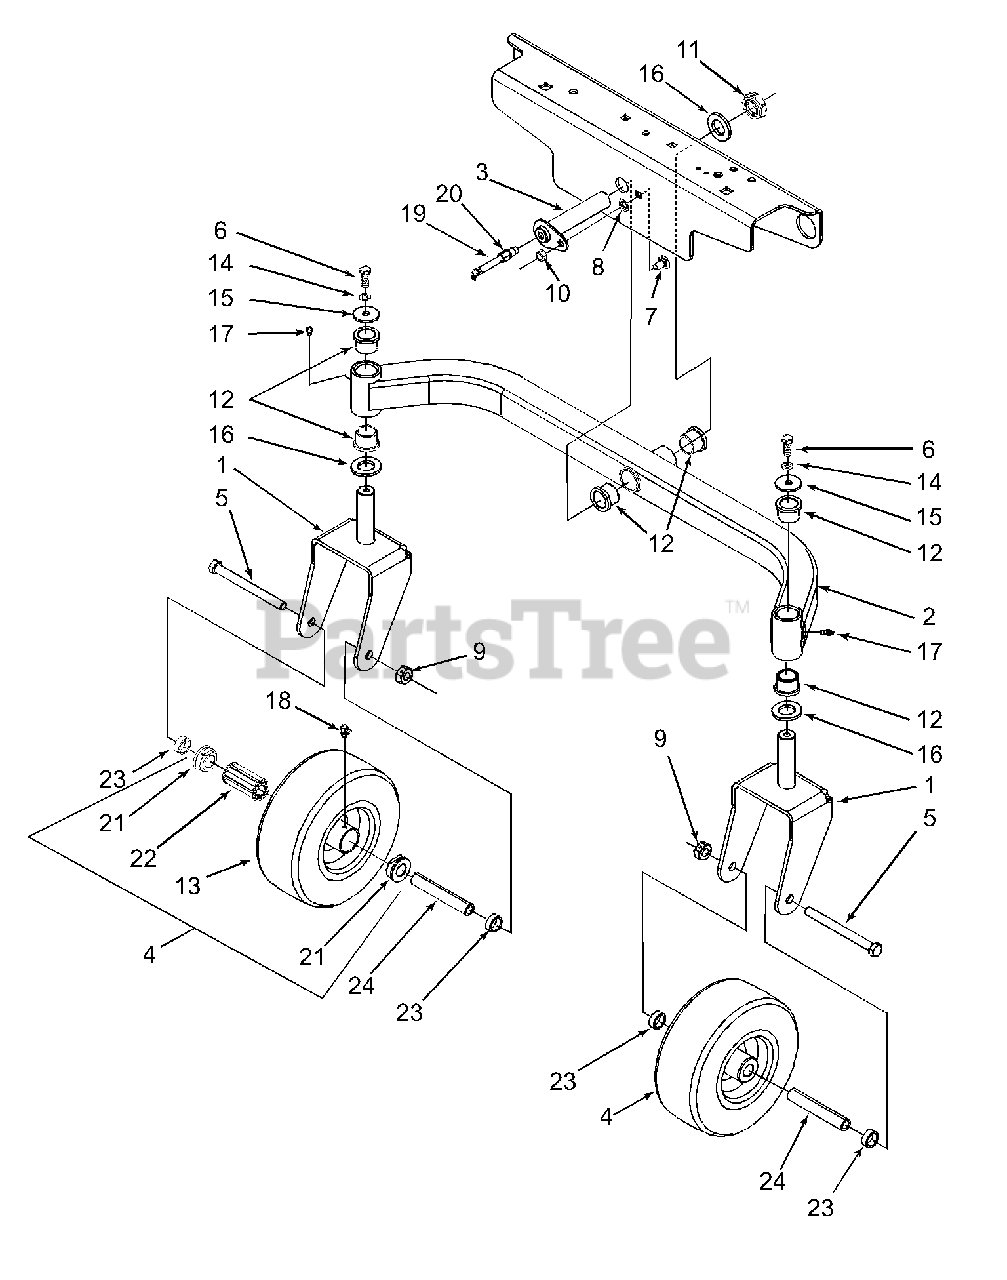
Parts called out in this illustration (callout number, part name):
4	Wheel Comp 11.0 x 4.0 x 5.0
5	Screw, Hex Cap, 1/2-20 x 5.5
6	Screw, Hex Cap, 3/8-16 x 1.0 GR5
7	Bolt, Carriage, 3/8-16 x .75
8	Push Nut, Retainer, 3/8 ID
9	Nut, Hex Center Lock, 1/2-20
10	Nut, Hex Flange Lock, 3/8-16
11	Nut, Hex Lock, 1.0-14
12	Bearing, Flange, 1.0 ID
13	Tire, Urethane, Only
14	Washer, Lock 3/8
15	Washer, Flat, .39 x 1.5 x .134
16	Washer, Special Flat
17	Fitting, Grease
18	Fitting, Grease, 90° Tap 1/4-28
19	Fitting, Grease, 65° w/Extension
20	Adapter, 1/8 NPTF x 1/8 NPTF
21	Bearing, Flange
22	Bearing, Roller
23	Spacer, .79 ID x .347 Lg
24	Spacer, Wheel
